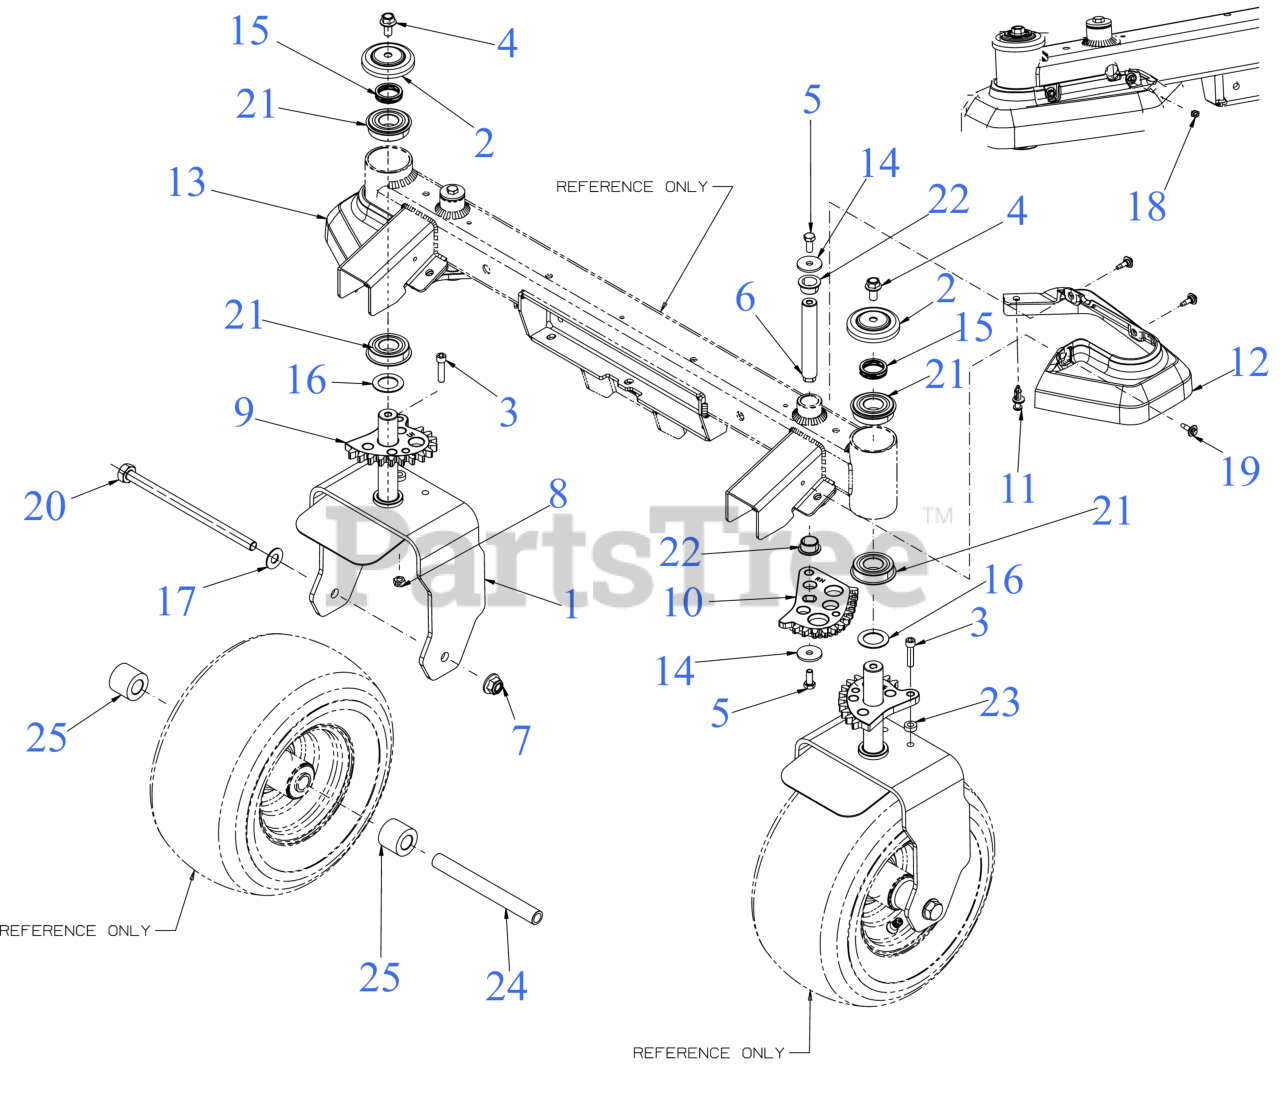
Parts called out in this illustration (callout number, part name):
1	CASTER WHEEL YOKE
3	SCREW 5/16-18X1.25
4	BOLT - 3/8-16:.75:GR5:PATCH LOCK
5	SCREW 5/16-18 x .750
6	STEERING GEAR PIVOT SHAFT
9	STEERING SPUR GEAR 13T
10	STEERING GEAR 12T
11	PLASTIC RIVET
12	STEERING GEAR COVER (RH)
13	STEERING GEAR COVER (LH)
14	WASHER-5/16 x 1.25X 1.27
15	WAVE WASHER
16	WASHER 1.010X1.560X.060
17	FLAT WASHER
18	GREASE ZERT 1/4-28
19	SHOULDER SCREW M6-1 .368 X.115
20	SCREW-1/2-13X8.5 GR5 FLG RZF-SX
21	BALL BEARING 25X52X15
22	FLANGE BEARING .75x.875x.50
23	SPACER .376ID X.625X.22
24	CASTER AXLE SPACER
25	CASTER WHEEL SPACER
